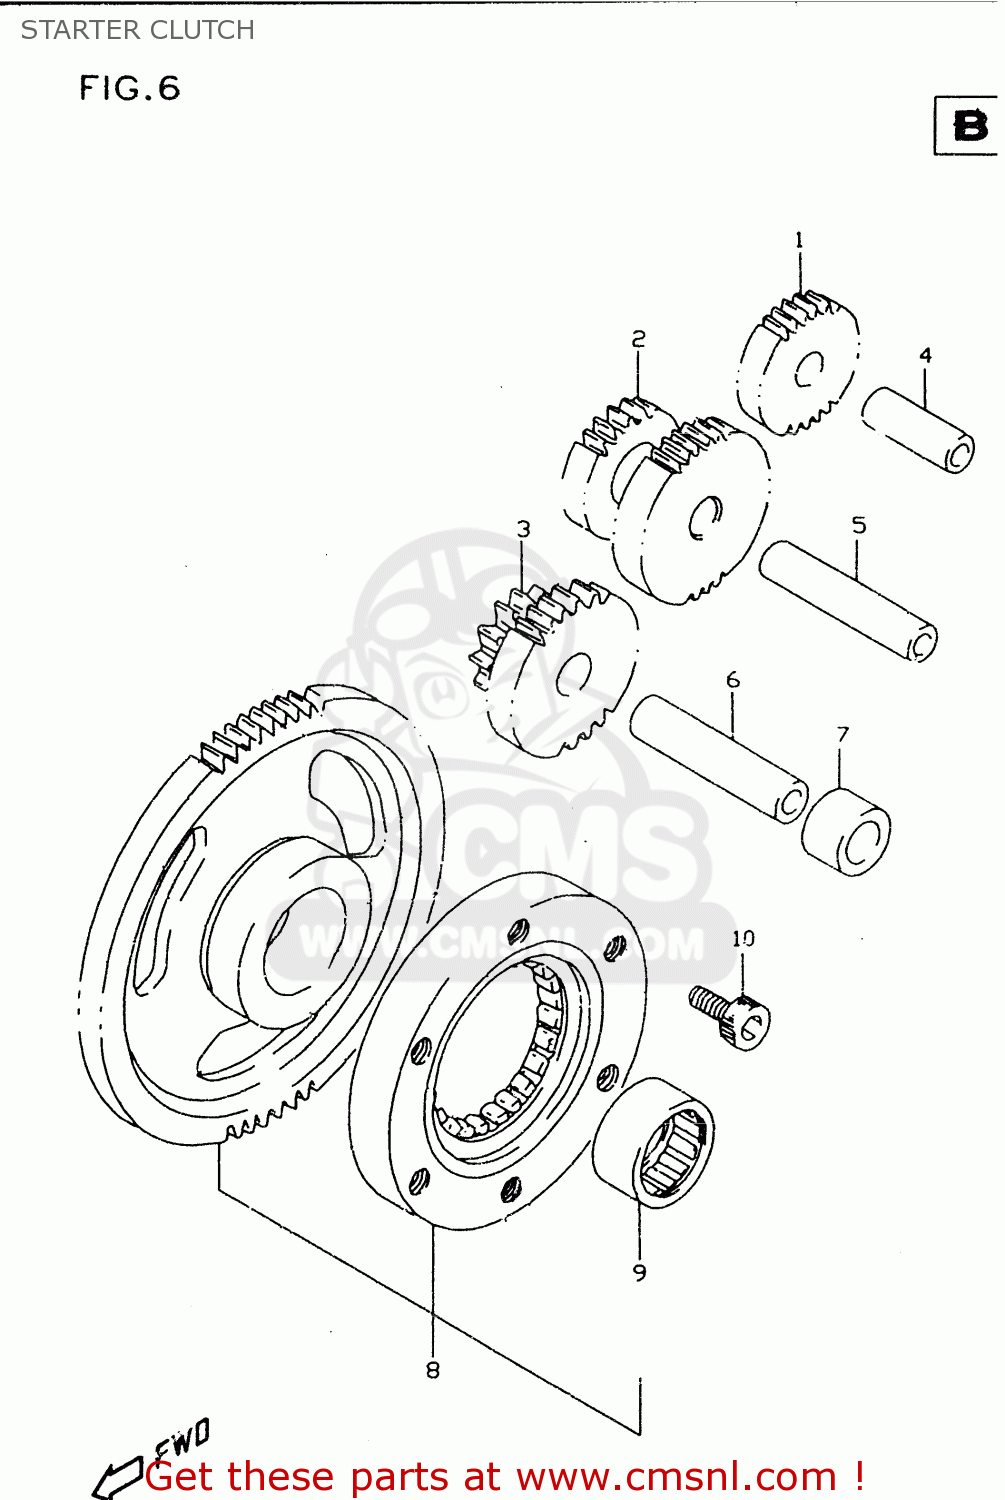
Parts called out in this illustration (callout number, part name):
1	GEAR,STARTER IDLE NO.1(NT:34)
2	GEAR,STRTR IDLE NO.2(NT:22/47)
3	GEAR,STARTER IDLE NO.3
4	PIN(6X10X32)
5	PIN(6X10X55.5)
6	PIN(12X55.5)
7	SPACER(12.5X19X13)
8	CLUTCH SET,STARTER
9	BEARING(29X36X18)
10	BOLT
